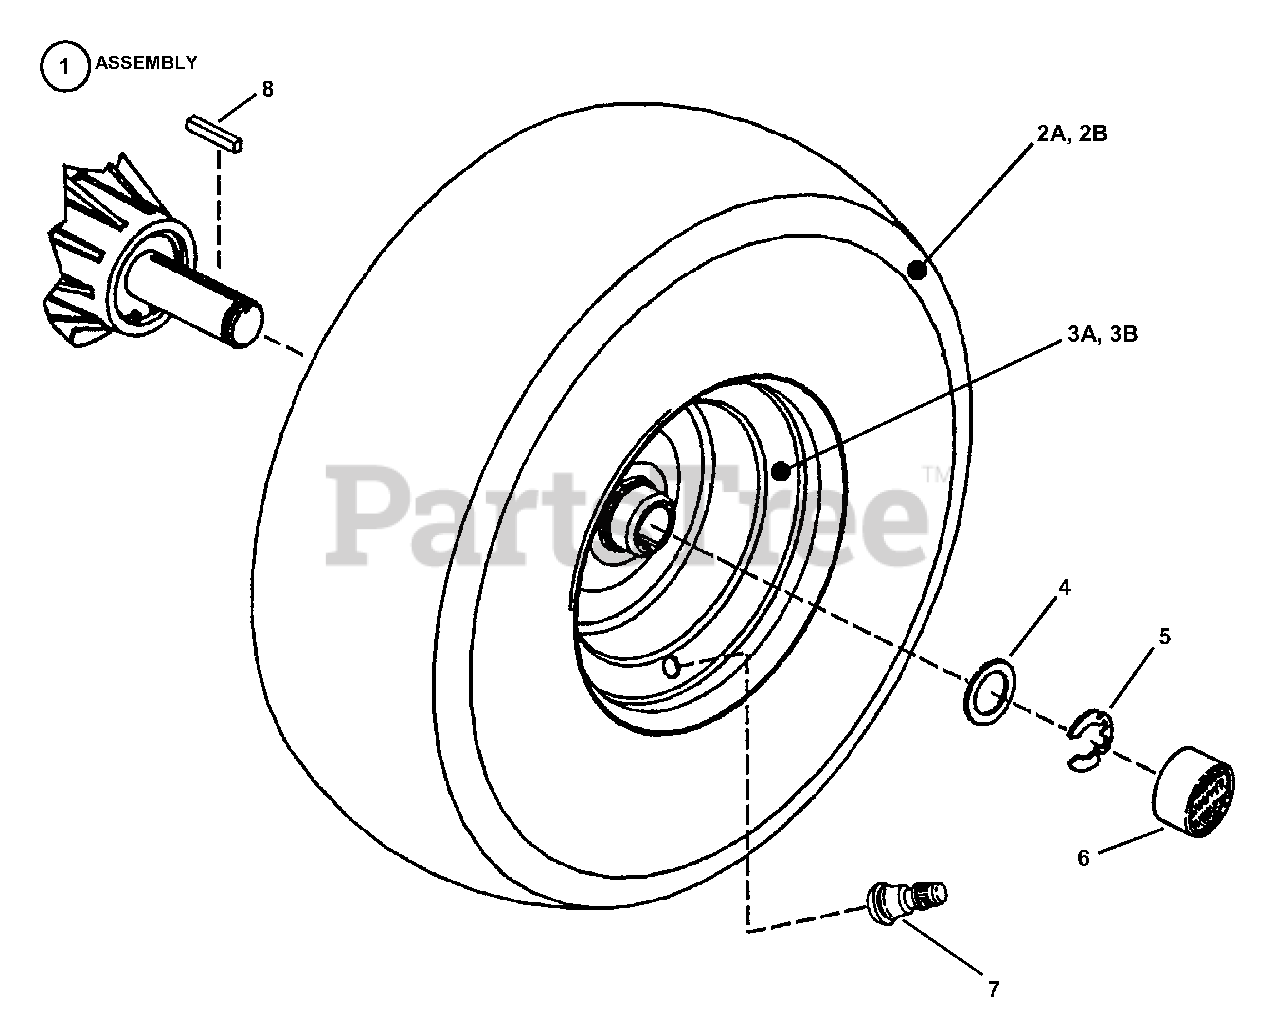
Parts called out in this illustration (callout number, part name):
1	ASSEMBLY, Rear Tire & Rim
2A	TIRE, 18 x 7.00-8, Multi-Trac (33" Models)
2B	TIRE, 18 x 8.50-8, Multi-Trac (38" Models)
3A	RIM, 18 x 6.50 (33" Models)
3B	RIM, 18 x 8.50 (38" Models)
4	BUSHING, Machine
5	RING, Retaining, External 1"
6	CAP, Hub
7	STEM, Valve
8	KEY, Square M6 x 38mm
